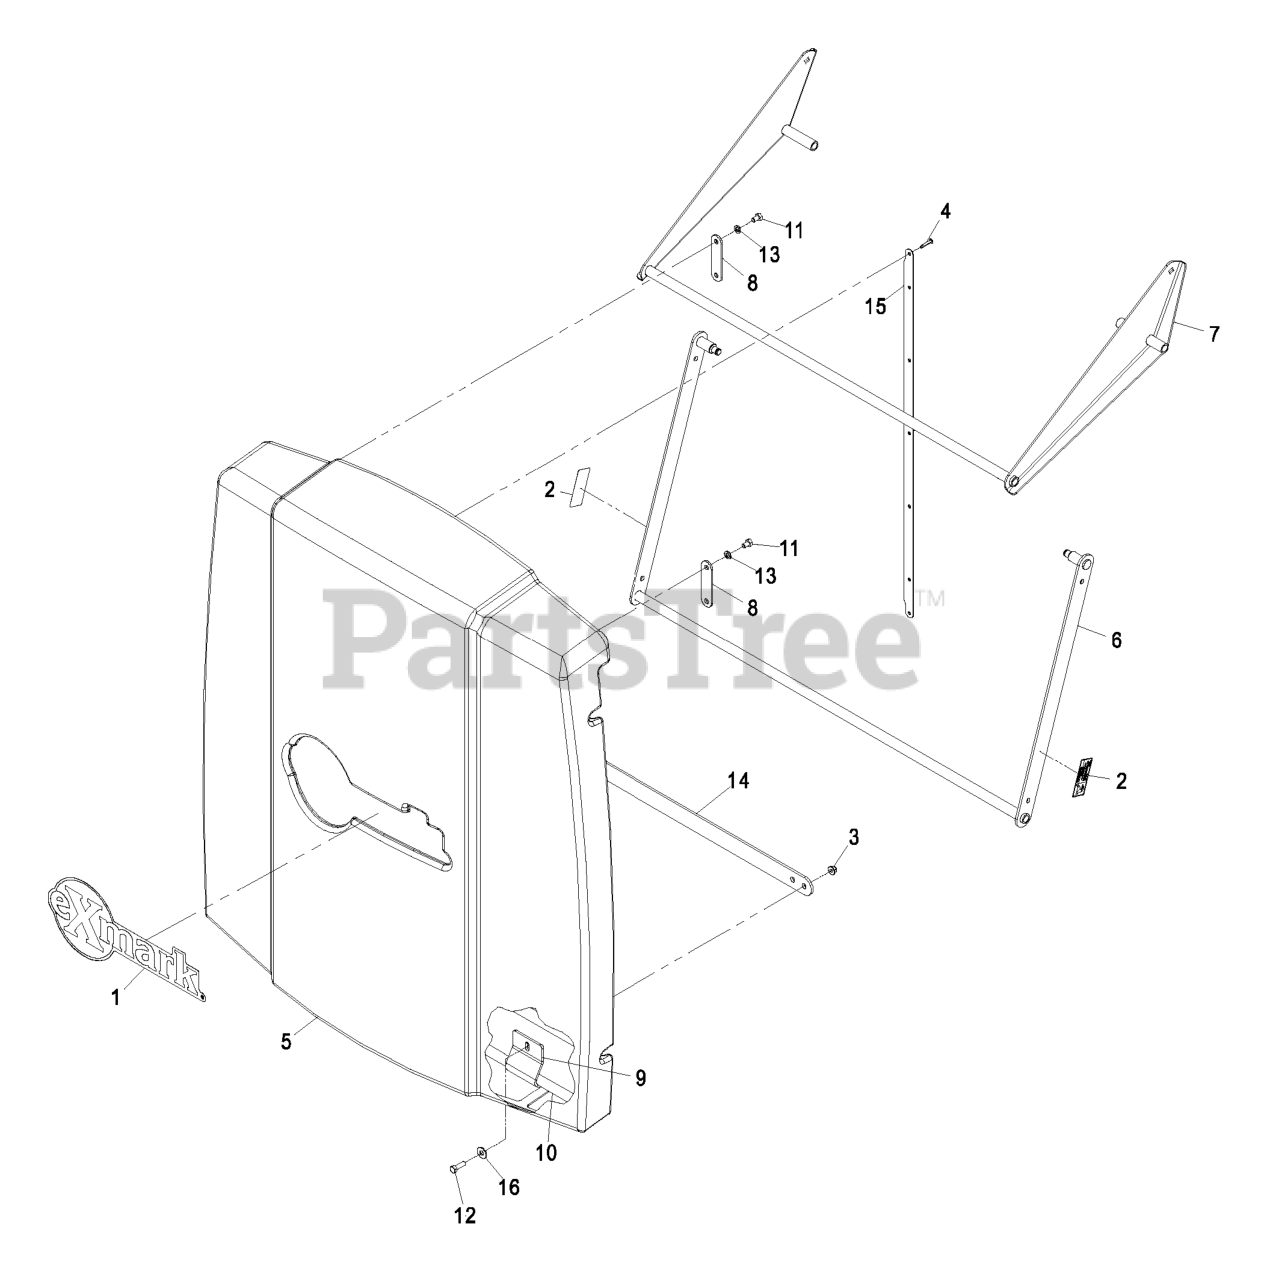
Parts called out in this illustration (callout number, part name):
1	DECAL,EXMARK LOGO
2	DECAL-PINCH POINT
3	NUT-HF, NI
5	Asm, Door W/Decal
7	WLD,FR DOOR UPR PVT
8	STRAP,FR DOOR PIVOT
9	PLATE,FRUVD DOOR LATCH
10	TUBE,FRUVD DOOR
11	SCREW-HH
12	SCREW-HH
13	WASHER-LOCK
14	PLATE,FRUVD DOOR REINF
15	ASM,FRUVD DR BRACE SVC
16	WASHER-FLAT
